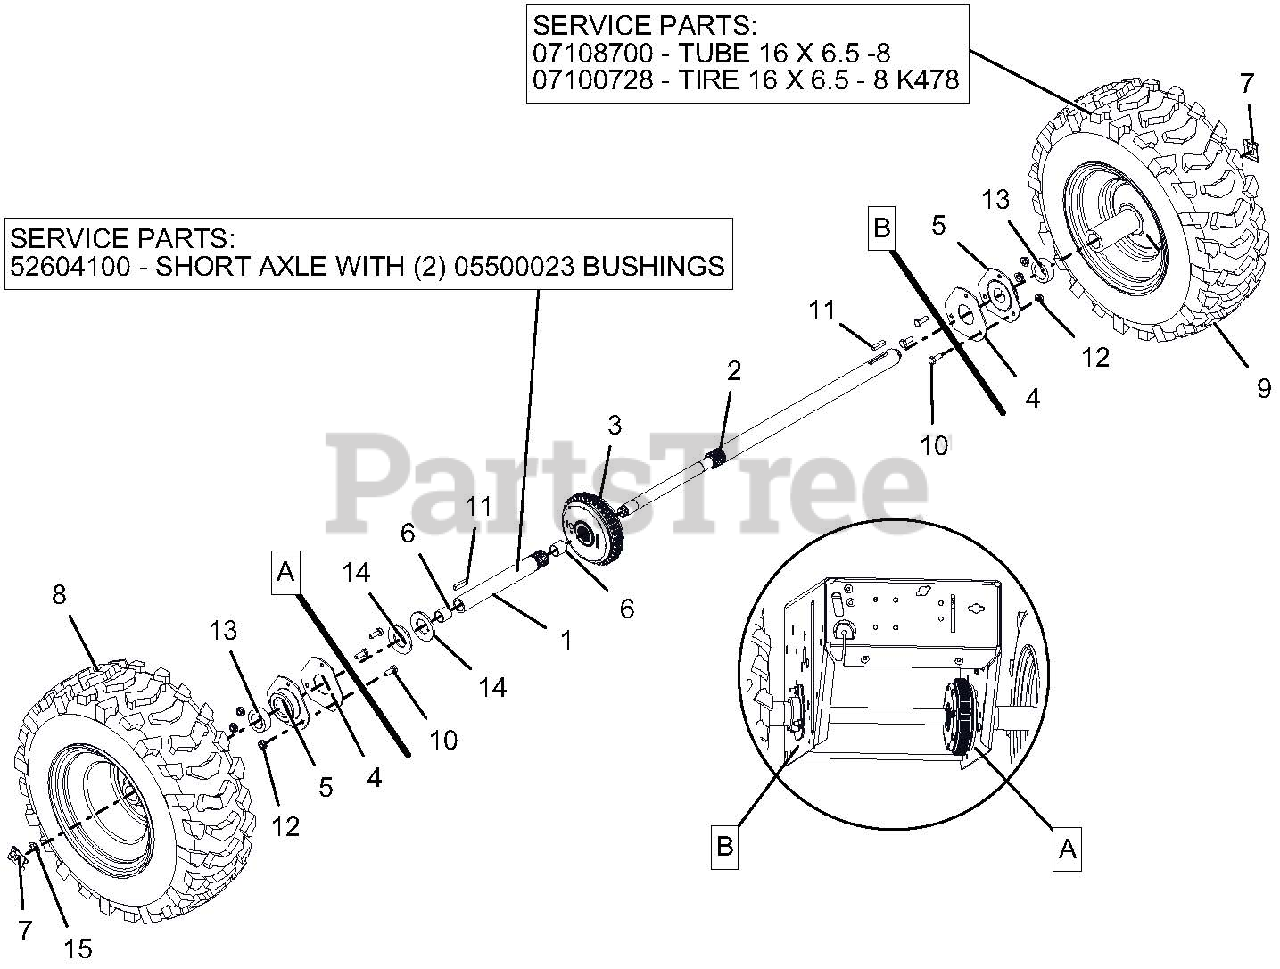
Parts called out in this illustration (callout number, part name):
1	AXLE, SHORT-PRO AUTO DIFF
1	AXLE, SHORT-AUTO W/BUSHINGS
1	BSHG-SLV .706X.764X.75 BRZ
2	AXLE, LONG-PRO AUTO DIFF
3	DIFFERENTIAL, AUTOMATIC
4	PLATE, BEARING SPACER
5	BRG-FLG 1.003/1.000 3 BOLT
6	BSHG-SLV .706X.764X.75 BRZ
7	CLIP, SNAP .625 DIA
8	TIRE/WHEEL, RH 16X6.50-8 DIFF
9	TIRE/WHEEL, LH 16X6.50-8 DIFF
9	TUBE
9	TIRE, 16X6.50-8 K478
10	@BLT-HEX .25-20X.75 GR5 YWZC
11	KEY-RECT .25X.188X1.00
12	@NUT-LK-CTR-FLG .25-20 YWZC
13	SPACER, PRO AXLE BEARING
14	WSHR-FL-STL- 1.062X2.0X.134 YZ
15	RG-RTNG-EXT .625X.042
